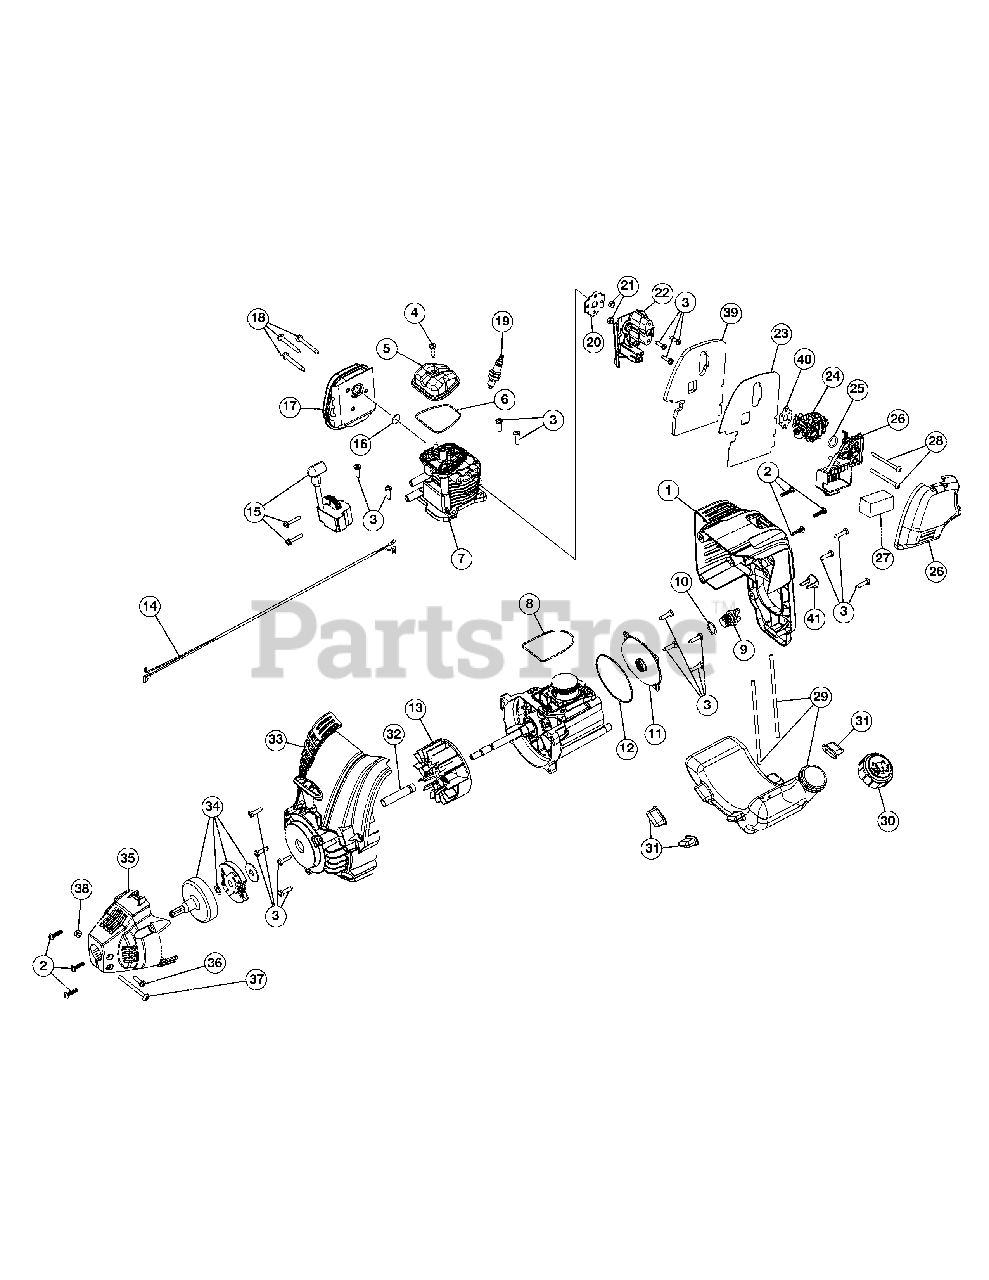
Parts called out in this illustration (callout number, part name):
1	Engine Cover Assembly (Incl. 2 & 3)
2	Cover Screw
3	Housing Screw
4	Rocker Cover Screw
5	Rocker Cover
6	Rocker Cover O-Ring
7	Cylinder Assembly (Incl. 3 - 6 & 8)
8	Cylinder O-Ring
9	Oil Plug (Incl. 10)
10	Oil Plug O-Ring
11	Crankcase Cover
12	Crankcase Cover O-Ring
13	Flywheel Assembly
14	Lead Wires
15	Module Assembly
16	Muffler Gasket
17	Muffler Assembly (Incl. 16 & 18)
18	Muffler Screw
19	Spark Plug
20	Insulator Gasket
22	Insulator
23	Carburetor Gasket
24	Carburetor
26	Air Cleaner Cover Assembly (Incl. 27)
27	Air Filter
29	Fuel Tank Assembly w/Fuel Lines (Incl. 30)
30	Fuel Cap
31	Fuel Tank Pads
32	Spacer
33	Starter Housing Assembly (Incl. 3)
34	Clutch Assembly
35	Clutch Cover (Incl. 2)
36	Anti-Rotation Screw
37	Clamp Screw
39	Heatshield Carb.
41	Electric Start Plug
